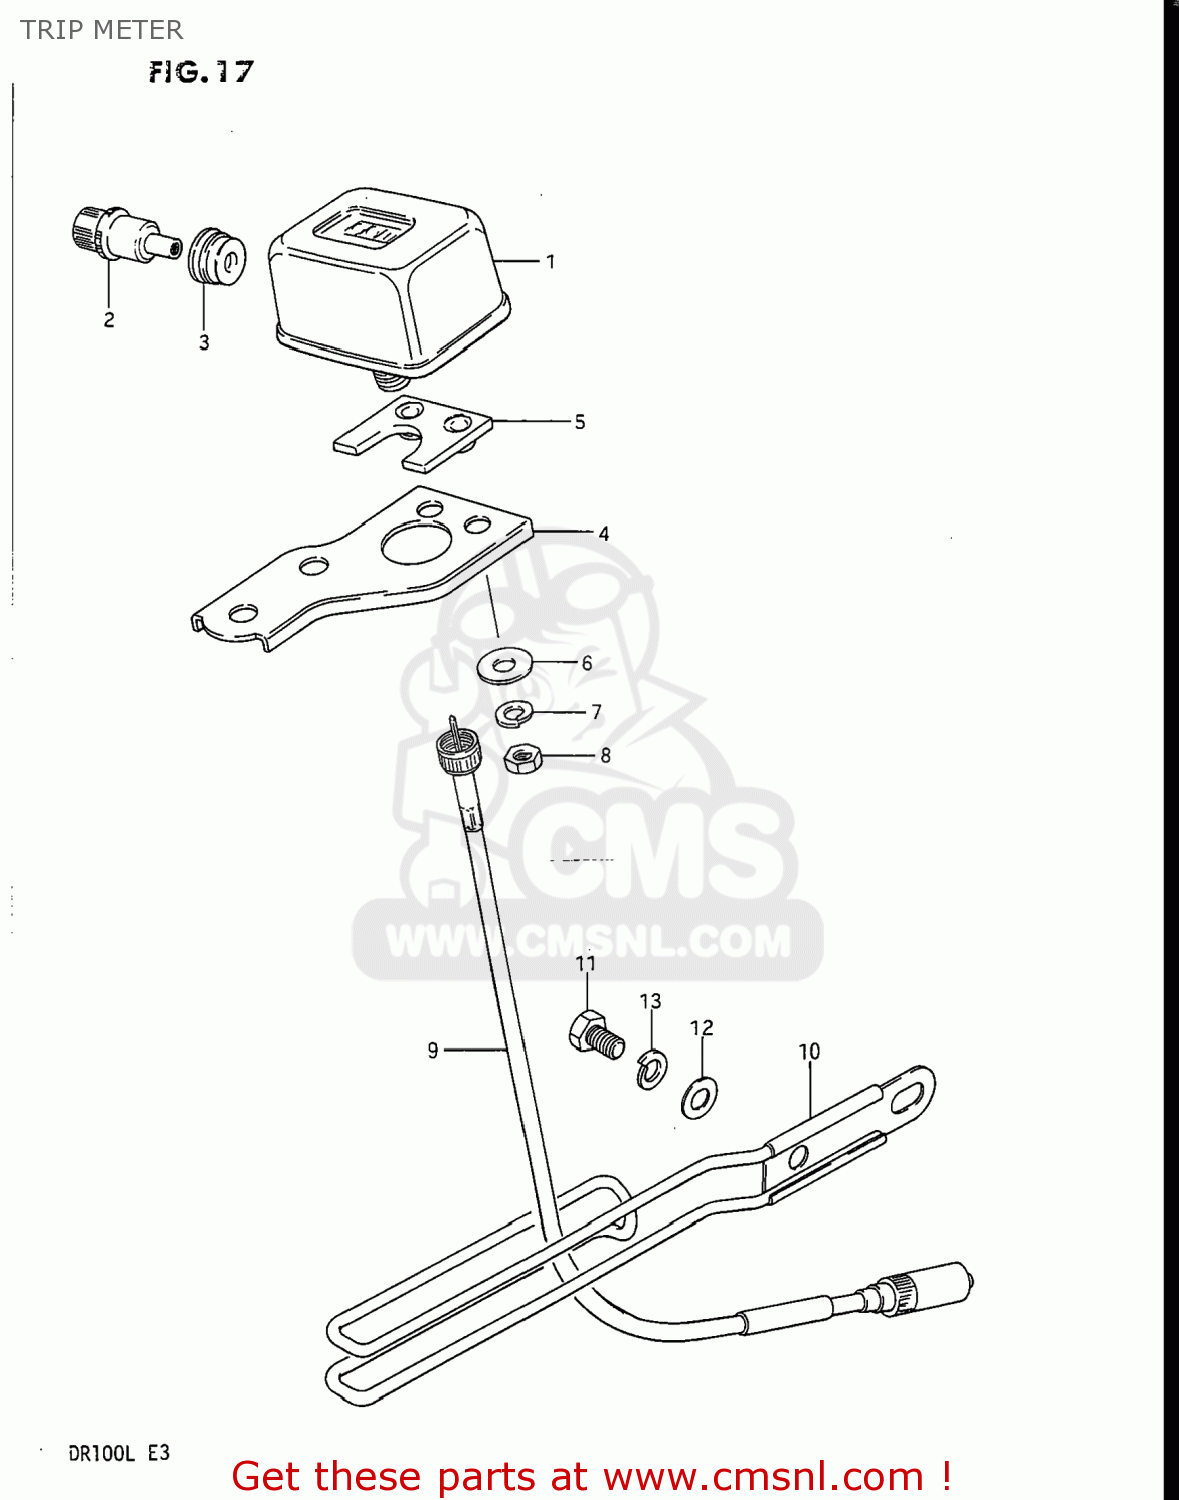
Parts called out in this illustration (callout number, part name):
1	TRIP METER
2	KNOB,TRIP METER
3	COVER,TRIPMETER KNOB
4	BRACKET,TRIPMETER
5	CUSHION,TRIPMETER
6	WASHER,METER
7	WASHER,LOCK 4M
8	NUT
9	CABLE ASSEMBLY,SPEEDOMETER
10	GUIDE,CABLE
11	BOLT 8X12
12	WASHER
13	LOCK WASHER
